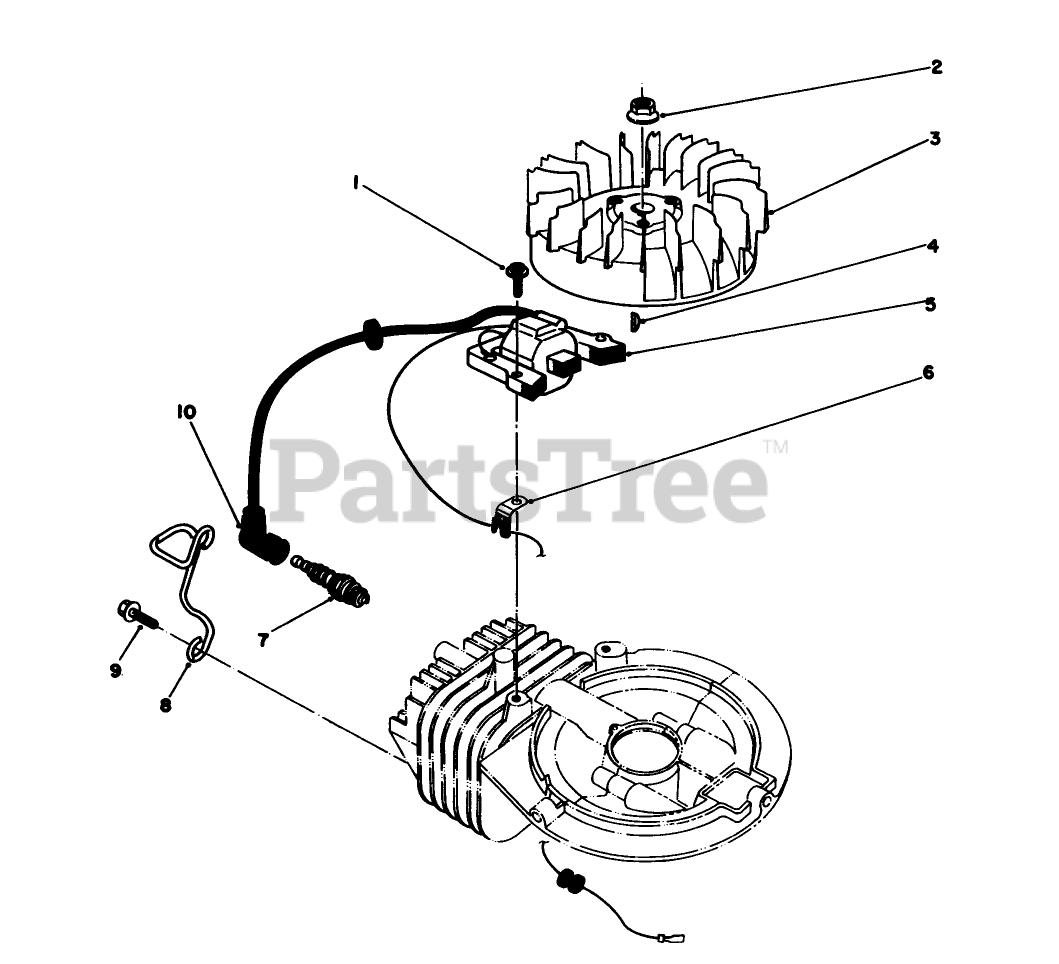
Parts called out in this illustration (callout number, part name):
1	SCREW
3	FLYWHEEL
5	COIL-MAGNETO
6	CLAMP
7	Sparkplug
8	PROTECTOR-PLUG
9	SCREW
10	CAP-SPARKPLUG
